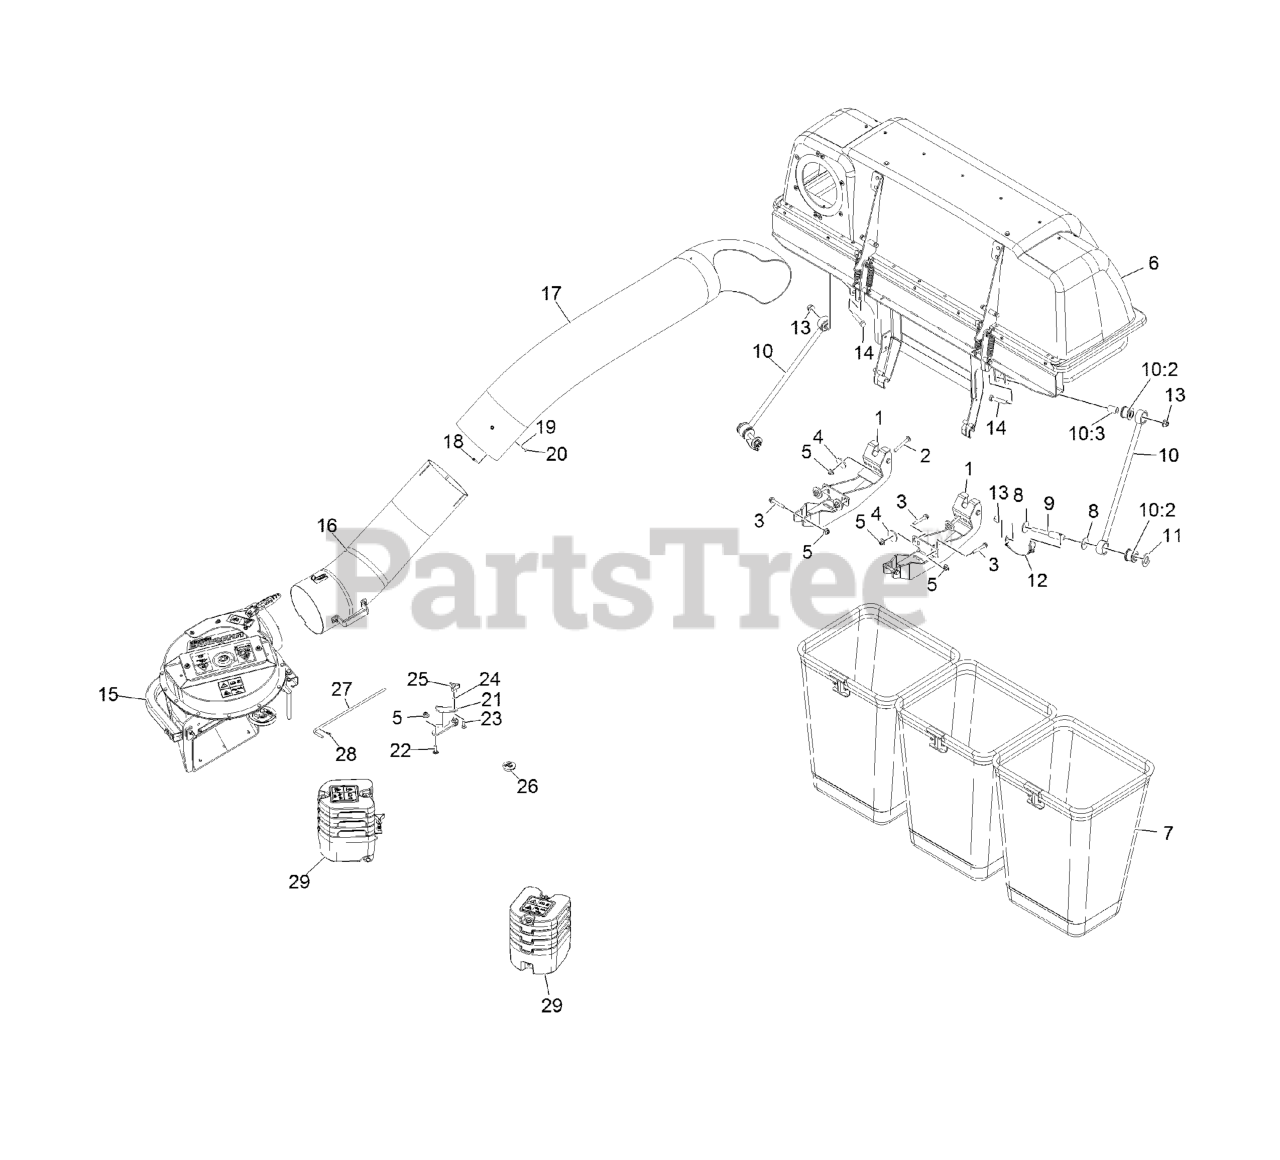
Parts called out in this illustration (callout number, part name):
1	MOUNT-BAGGER, LOWER
2	SCREW-CARR
3	Screw-HHF
4	Washer-Plain
5	Nut-Nyloc 3/8-16 Flg
7	BAG AND FRAME ASM
8	WASHER-THRUST
9	PIN-BAGGER BRKT
10	SUPPORT ROD ASM
10:2	BUSHING-RUBBER
11	Washer-Flat
12	PIN-MOUNT, BAGGER
13	Nut-Lock 1/2-13
14	SCREW-HH
15	ASM, BLOWER LARGE - SVC ONLY
16	LOWER TUBE ASM
17	TUBE-UPPER
18	SCREW-HWH
19	WASHER-FLAT
20	NUT-LOCK, NI
21	BRACKET,BELT COVER
22	Bolt-Carriage 3/8-16 X 1 1/4
23	BOLT-CARR
24	RING-RETAINING, BOLT
25	KNOB-3 PRONG
26	PLUG, BLACK NYLON 1.75
27	PIN,CHUTE PIVOT
28	PIN-COTTER
29	Caster Weight ASM
